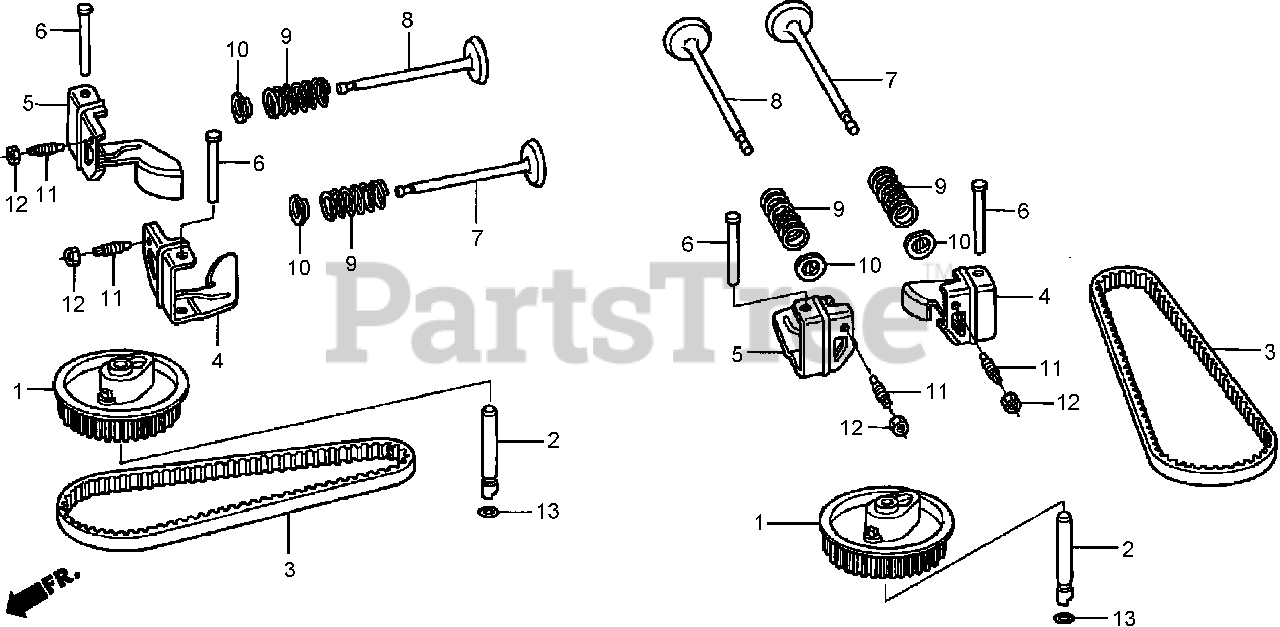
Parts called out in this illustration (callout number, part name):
1	PULLEY-CAMSHAFT
2	SHAFT-PULLEY, CAM
3	BELT-TIMING (97HU8 G-200)
4	ARM-VALVE ROCKER, INTAKE
5	ARM-VALVE ROCKER, EXHAUST
6	SHAFT-ARM, ROCKER
7	VALVE-INTAKE
8	VALVE-EXHAUST
9	Spring-Valve
10	RETAINER-SPRING, VALVE (INTAKE)
11	SCREW-ADJUSTING, TAPPET
12	NUT-ADJUSTING, TAPPET
13	O-RING (6.8X19) (ARAI)
